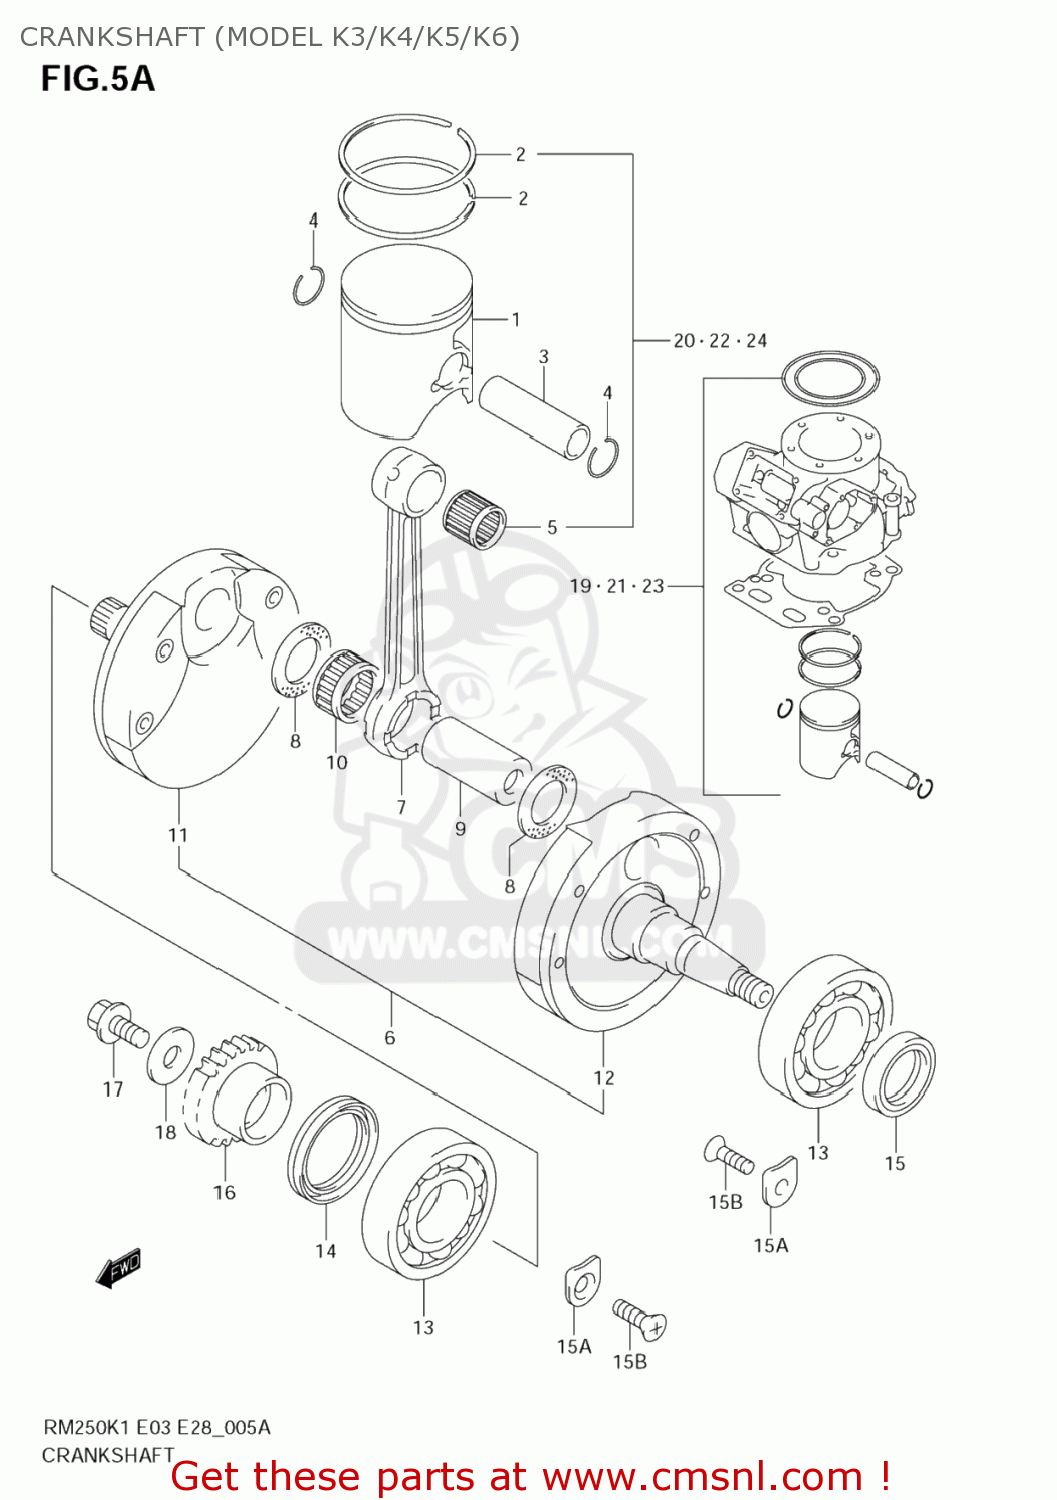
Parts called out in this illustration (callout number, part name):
1	PISTON
2	RING,PISTON
3	PIN,PISTON
4	CIRCLIP
5	BEARING(18X23X22)
6	CRANKSHAFT ASSY
7	CONNECTING ROD
8	WASHER(24X39X1)
9	PIN,CRANK
10	BEARING(24X30X20)
11	CRANKSHAFT,R
12	CRANKSHAFT,L
13	BEARING(28X68X18)
14	SEAL,OIL(27X52X8)
15	SEAL,OIL(25X37X7)
15A	RETAINER,CRANKSHAFT BEARING
15B	SCREW
16	GEAR,PRIMARY DRIVE
17	BOLT(10X20)
18	WASHER
19	PISTON
20	PISTON
21	PISTON
22	PISTON
23	PISTON
24	PISTON
